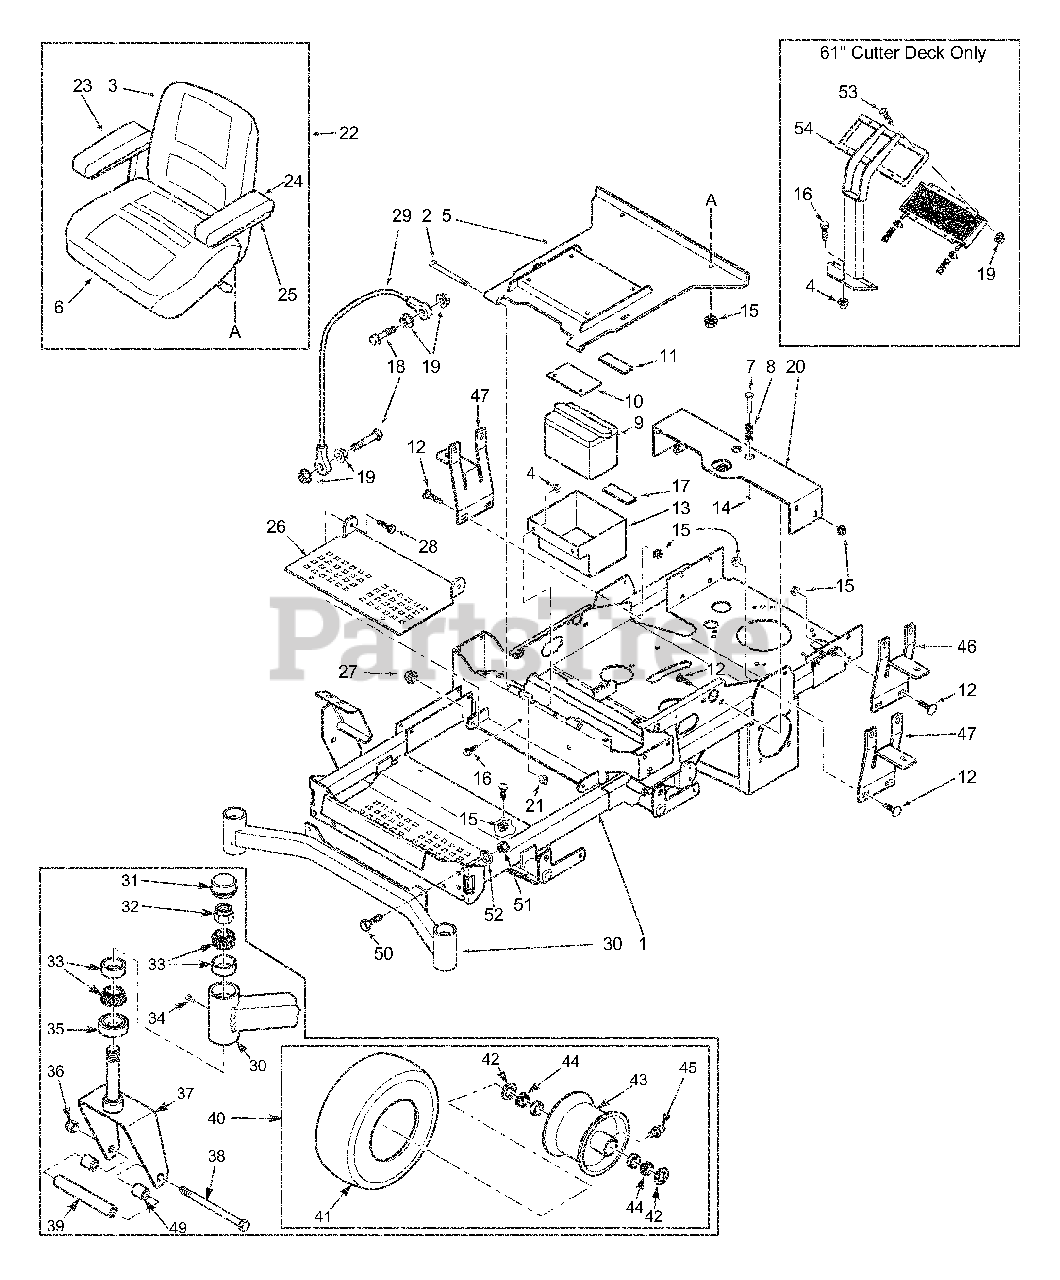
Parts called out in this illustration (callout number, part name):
1	Main Frame Assembly w/decals
2	Bolt, Hex Head 5/16-18 x 3-3/4"
3	Cushion, Back
4	Nut, Serr. Flange 3/8-16
5	Plate, Seat Mounting
6	Cushion, Lower Seat
7	Pin Retainer, Spring
8	Spring
9	Battery
10	Battery Cover
11	Battery Hold Down Pad
12	Bolt, Carr. 5/16-18 x 3/4"
13	Battery Box
14	Roll Pin, Spring 5/32 x 3/4"
15	Nut, Serr. Flange 5/16-18
16	Bolt, Hex Head 3/8-16 x 1"
17	Pad, Rubber
18	Bolt, Hex Head 1/4-20 x 1-1/4"
19	Nut, Serr. Flange 1/4-20
20	Seat Base Support
21	Nut, Elastic Stop 5/16-18
22	Seat Assembly w/ adj. rails
23	Arm Pad, RH
24	Arm Pad, LH
25	Channel, Armrest
26	Footplate
27	Nut, Elastic Stop 3/8-16
28	Bolt, Hex Head 3/8-16 x 1"
29	Cable, Seat Stop
30	Weldment, Caster Support
31	Cap, Grease
32	Nut, Elastic Stop 1.0-14
33	Bearing Set
34	Plug, 1/4-28
35	Seal, 2.0" OD x 1.625" ID
36	Nut, Elastic Stop 1/2-13
37	Yoke, Front Caster Wheel
38	Bolt, Hex Head 1/2-13 x 7-1/2"
39	Sleeve
40	Caster Wheel Assembly
41	Tire, 13 x 5.0-6 Smooth
43	Rim
44	Roller Bearing
45	Fitting, Grease
46	Mounting Bracket, Oil Tank
47	Mounting Bracket, Fuel Tank
49	Spacer, Caster Wheel
50	Bolt, Hex Head 7/16-14 x 1-1/4"
51	Nut, Elastic Stop 7/16-14
52	Lockwasher, 7/16
53	Bolt, Hex Head 1/4-20 x 5/8"
54	Support Weldment, Oil Cooler (61A)
